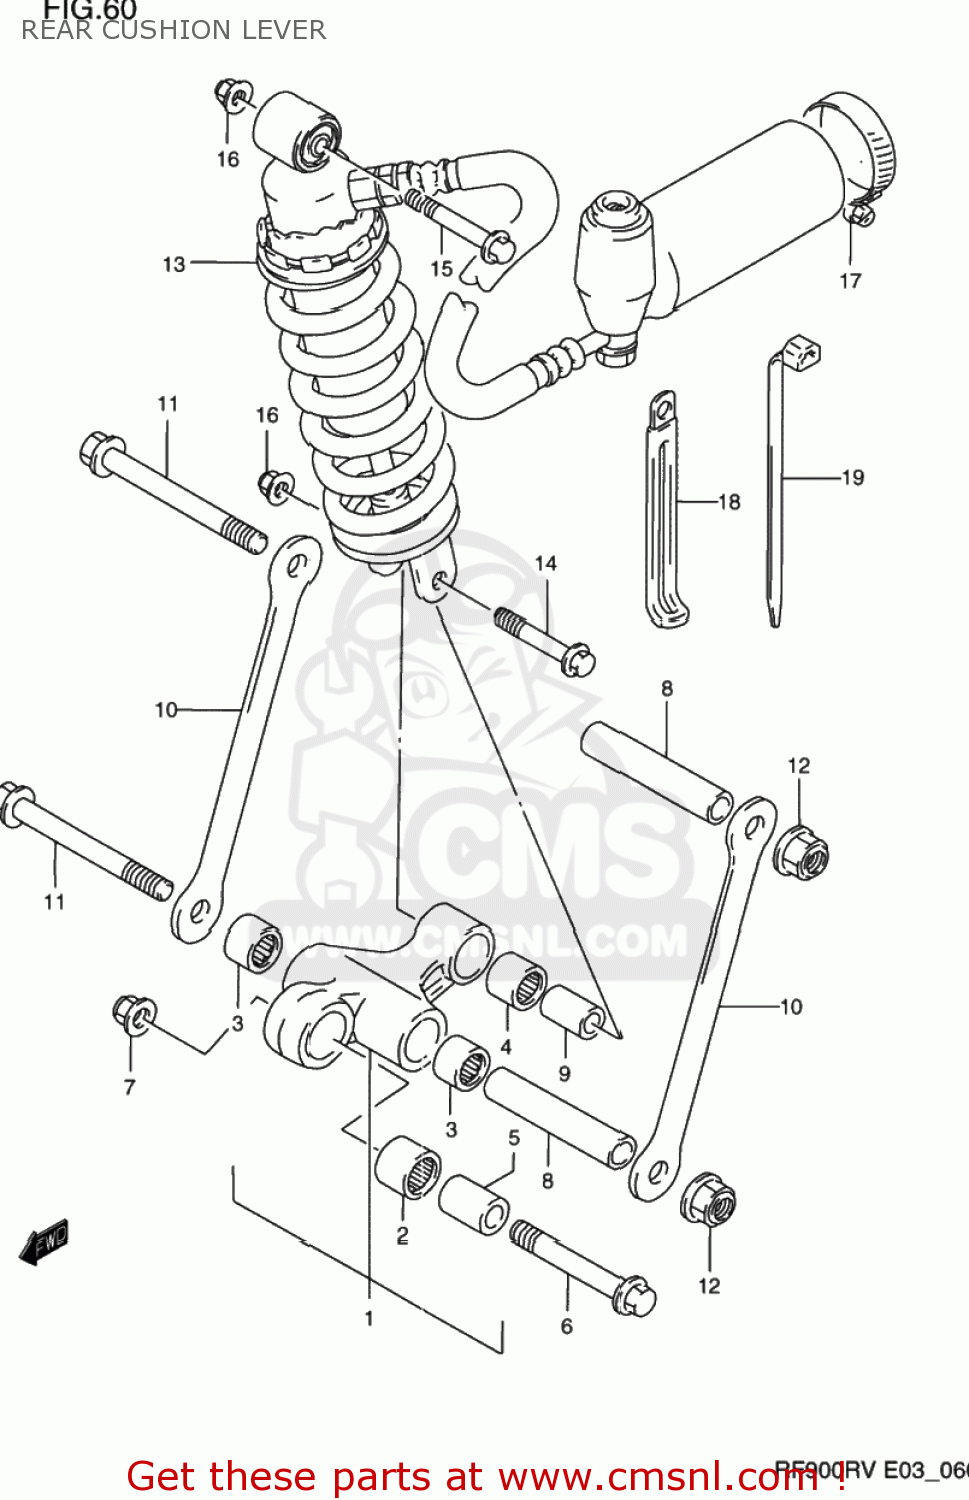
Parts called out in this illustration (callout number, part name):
1	LEVER SET,RR CUSHION
2	BEARING(20X27X26)
3	BEARING(17X24X25)
4	BEARING(17X24X26)
5	SPACER,RR CUSHION LEVER FR
6	BOLT,CUSHION LEVER FR
7	NUT 12MM
8	SPACER(12X17X85)
9	SPACER,RR CUSHION LEVER
10	ROD,REAR CUSHION LEVER
11	BOLT(12X115)
12	NUT 12MM
13	ABSORBER ASSY,RR SHOCK
14	BOLT(10X58)
15	BOLT(10X50)
16	NUT
17	CLAMP
18	CLAMP
19	CLAMP L:165
